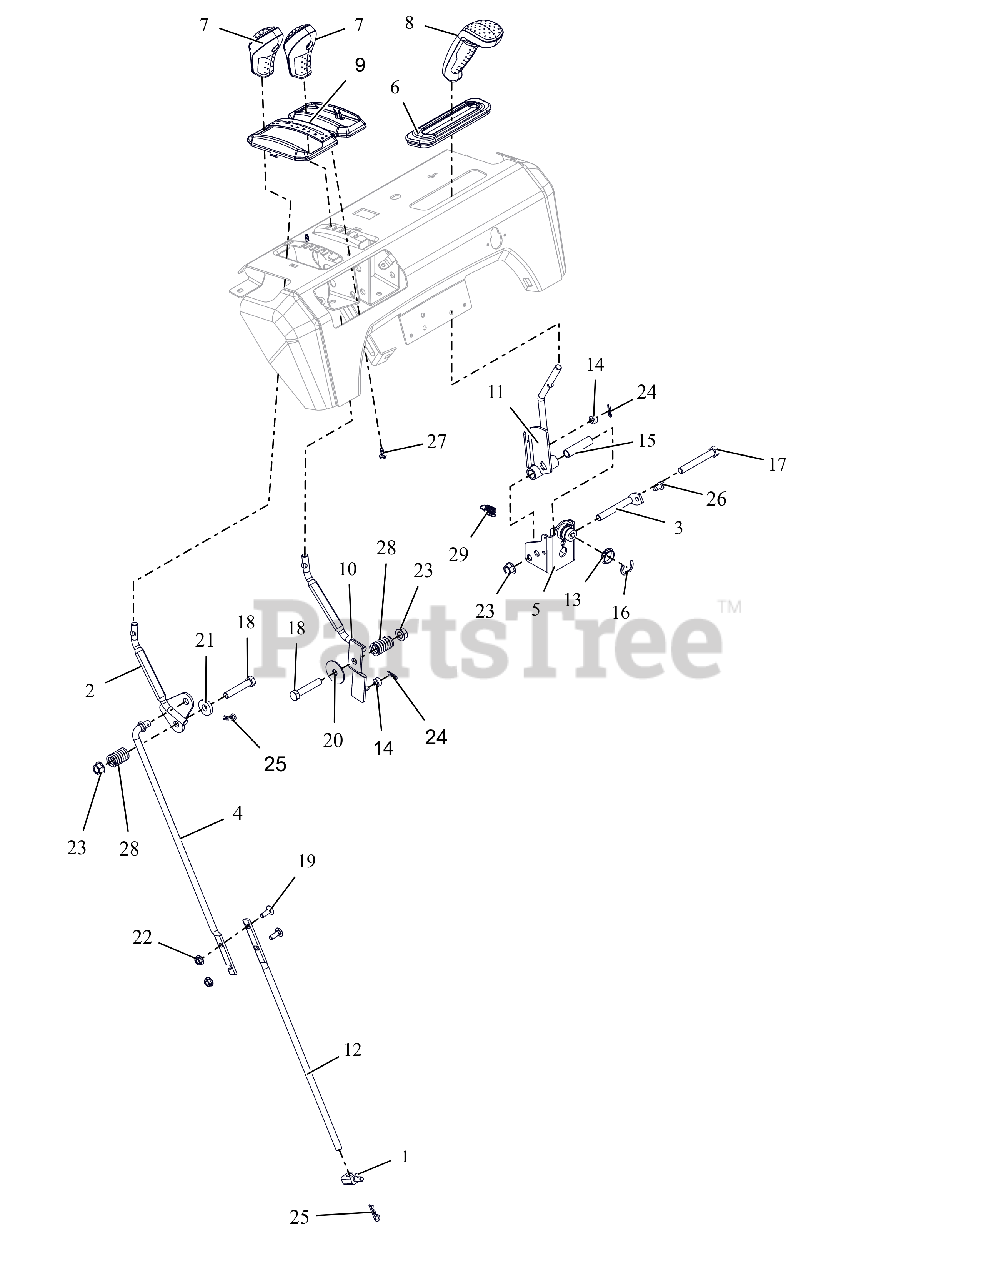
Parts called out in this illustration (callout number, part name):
1	PIVOT,SHIFT ROD .375-16(TRUNN)
2	WELDMENT,LG DASH SPEED CONTROL
3	ROD, PIVOT - INTERLOCK
4	ROD, SHIFT - UPPER
5	WELDMENT-CONTROL BRACKET-CHUTE
6	GROMMET, BOOT, QUICK TURN
7	KNOB, CONTROL, DASH
8	HANDLE, QUICK TURN, ASM
9	BEZEL, SHIFT - FRICTION SNOW
10	WELDMENT,LG DASH DEFL CONTROL
11	WELDMENT, CONTROL LEVER
12	ROD, SHIFT-LOWER (LG DASH DLX)
13	BUSHING, POLYLINER-.75 SNAPIN
14	BSHG-SLV .265X.500X.219
15	SPCR, WHEEL .385X.500X2.00
16	E-RING .750X.050
17	@BLT-HEX .38-16X2.75 GR5 YWZC
18	@BLT-HEX .38-16X2.00 GR5 YWZC
19	@BLT-RDHDSQNK .25-20X.75 G5YZ
20	WSHR-FL-STL .380X1.50X.062 YWZ
21	WSHR-FL-STL .406X1.00X.188 YWZ
22	@NUT-LK-CTR-FLG .25-20 YWZC
23	@NUT-LK-TOP-FLG .38-16 YWZC
24	PIN-HAIR INT .06X.18X.77
25	PIN-HAIR INT .08X.18X1.18 YWZC
26	SCR-TAP .25-20X.50 HWH TR YWZ
27	SCR-TAP #10X.50 BOSS INDHXHD
28	SG-COMP .125X.781X1.250
29	SPRING-EXT .047X.438X1.45
